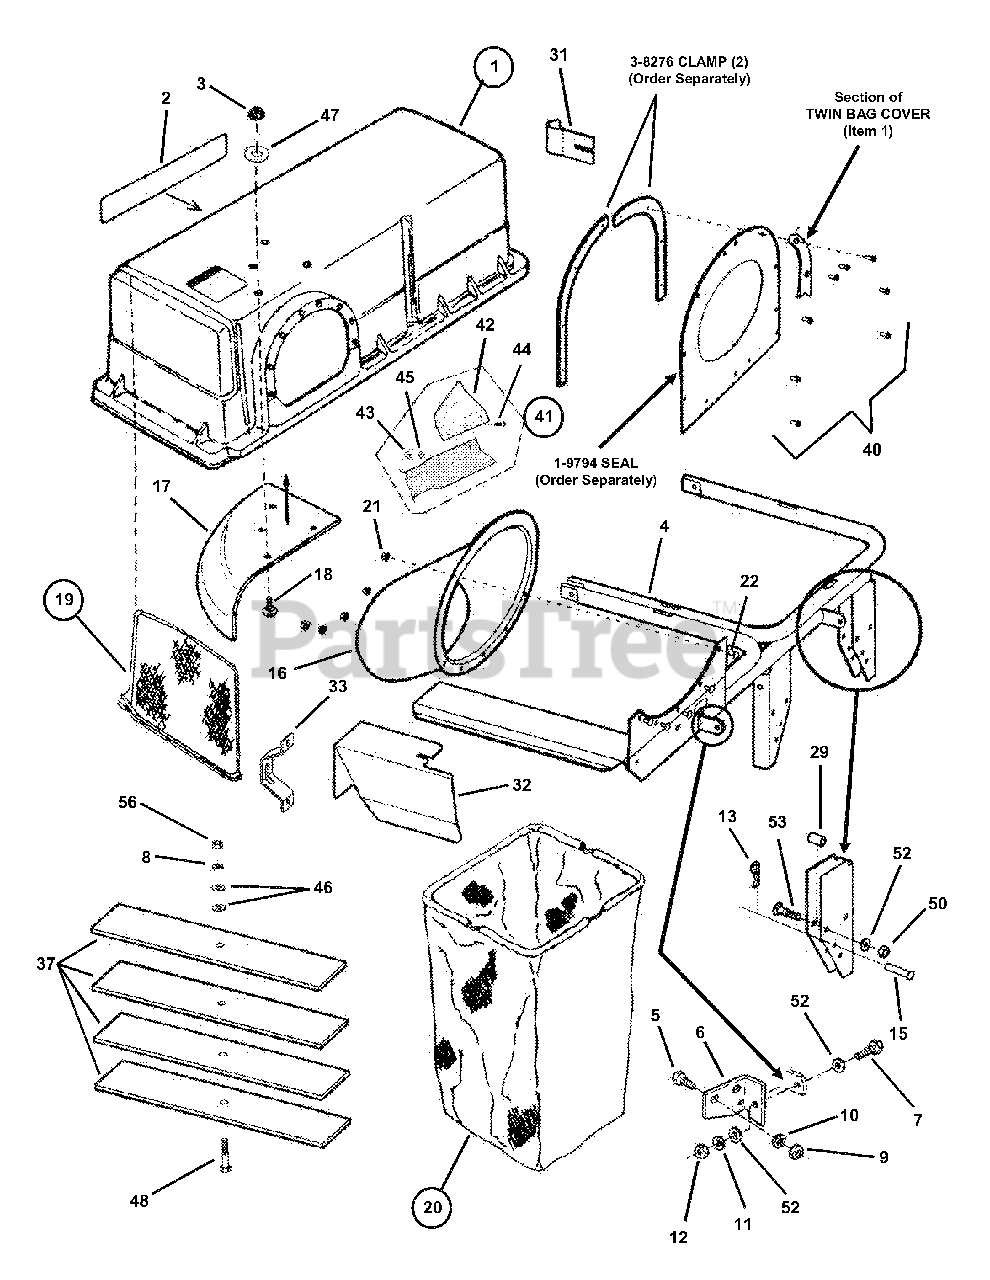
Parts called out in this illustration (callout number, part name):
1	ASS'Y, Cover
2	DECAL, Snapper
3	NUT, 1/4-20 Hex
4	WELDMENT, Frame
5	SCREW, 1/4-28 x 3/4"
6	HINGE, Top
7	SCREW, 5/16-24 x 1"
8	WASHER, 3/8" Flat
9	NUT, 1/4-28 Hex
10	WASHER, 1/4" Lock
11	WASHER, 5/16" Split
12	NUT, 5/16-24 Hex Ctr. Lock
13	PIN, 3/32 x 1-1/2" Hair
15	PIN, 5/16 x 1-11/16" Clevis
16	INLET, Twin Bagger
17	SECTOR
18	BOLT, 1/4-20 x 3/4" Carriage
19	ASS'Y, Screen (indented items)
20	ASS'Y, Bag (indented items)
21	NUT, 1/4-20 Hex Flange
22	BOLT, 1/4-20 x 1/2" Carriage
29	PAD, Bumper Mount
31	SUPPORT, Bumper
32	HEAT SHIELD, 14.5 HP
33	BRACE, Twin Bag Catcher
37	WEIGHT, Ballast
40	SCREW, #10-24 x 1/2" Tap
41	KIT, Air Lift
42	AIR LIFT
43	NUT, 5/16-24 Hex
44	SCREW, 5/16-24 x 21/32"
45	WASHER, 5/16" Internal Tooth Lock
46	WASHER, 3/8" Flat
47	WASHER, 1/4" Flat
48	SCREW, 3/8-16 x 2" Hex Hd. Cap
50	NUT, 5/16-18 Hex Ctr. Lock
52	WASHER, 5/16" Flat
53	BOLT, 5/16-18 x 1-1/2" Carr.
56	NUT, 3/8-16 Hex
